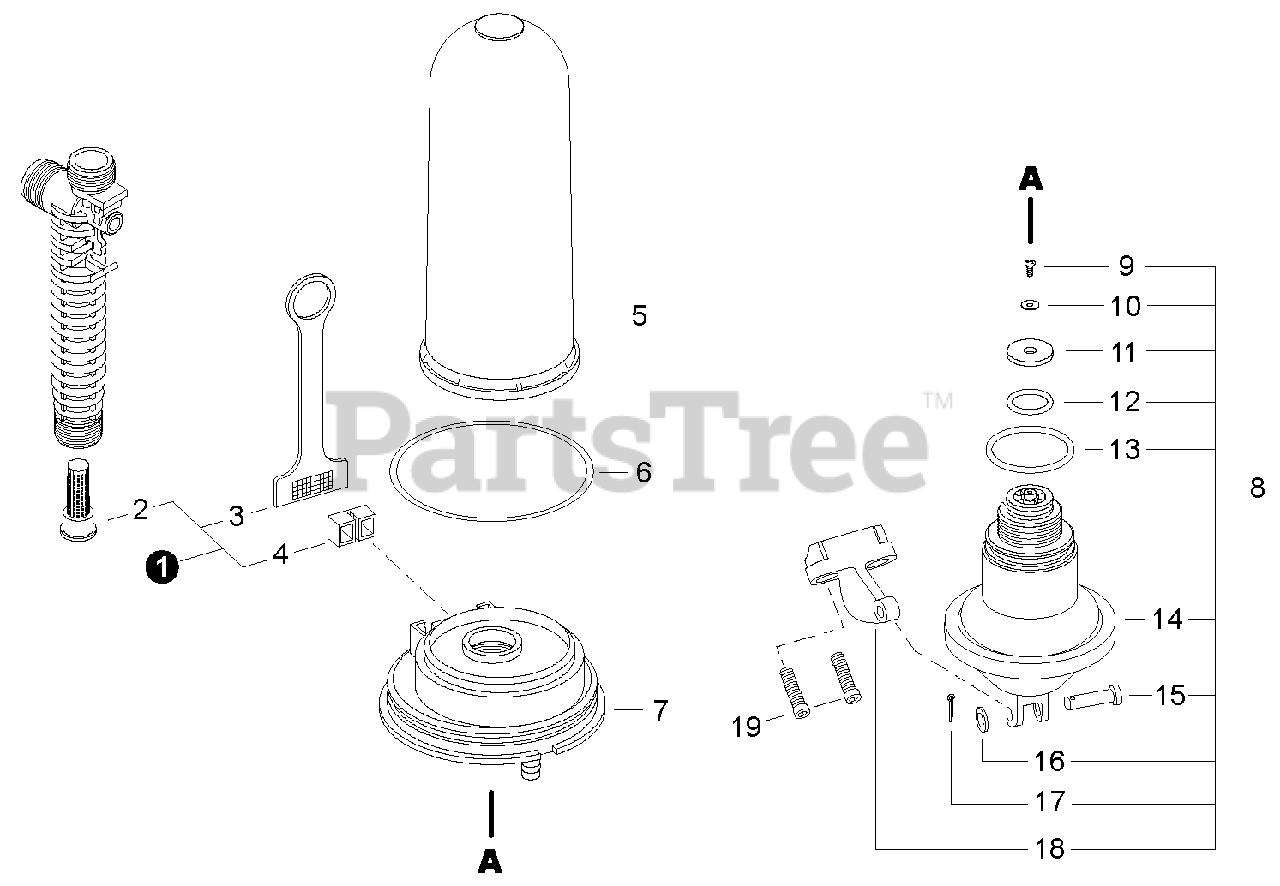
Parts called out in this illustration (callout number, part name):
1	FILTER KIT
2	FILTER, SPRAY GUN
3	FILTER, IN-TANK
4	FILTER, CARTRIDGE
5	CHAMBER, PRESSURE
6	O-RING, PRESSURE CHAMBER
7	BASE, PRESSURE CHAMBER
8	PUMP ASSY, DIAPHRAGM
9	SCREW, CYLINDER
10	WASHER, CYLINDER
11	SEAL, VALVE
12	O-RING, CYLINDER - SMALL
13	O-RING, CYLINDER - LARGE
14	PUMP, DIAPHRAGM
15	PIN, LEVER
16	WASHER, LEVER
17	PIN, COTTER
18	LEVER, PIVOT
19	SCREW, LEVER
